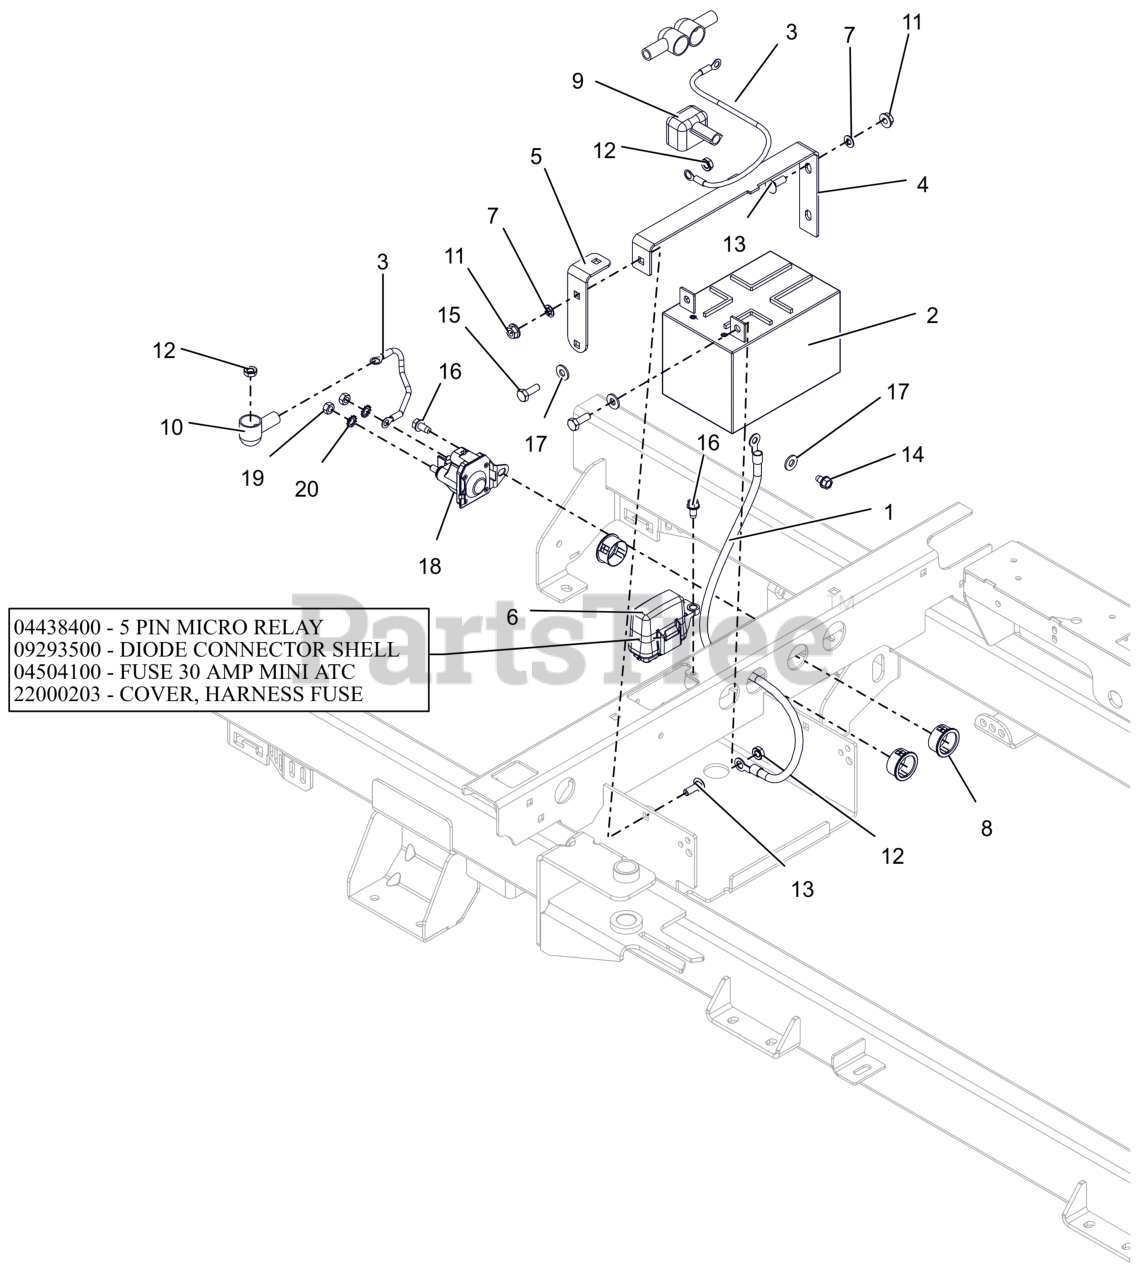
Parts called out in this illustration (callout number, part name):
1	CABLE-NEGATIVE BATTERY 24.00"
2	BATTERY, 12V 12A-190CCA
3	CABLE,POS W/2 1/4 RING 15.0 LG
4	BRKT, BATTERY HOLD-DOWN
5	BRKT, BATTERY HOLD DOWN
6	HARNESS, WIRE-4POS KEY IKON/ZT
6	RELAY,MICRO5 TERML W/RESISTOR
6	DIODE, CONNECTOR SHELL
6	FUSE,30 AMP MINI-ATC
6	COVER, FUSE
7	NUT-PUSH .25X.50 O.D.
8	BSHG, PANEL SNAP .937X1.11X.56
9	INSULATOR
10	BOOT, EYELET TERMINAL
11	NUT-LK-TOP-FLG .250-20 GF ZCC
12	NUT-KEPS .250-20 ZCC
13	BLT, RHSN .25-20X.750 G5 ZCC
14	SCR,TAP .25-20X.375 HWH TR ZCC
15	BLT, HEX .25-20X.75 G5 ZCC
16	SCR-TAP .25-20X.50 HWH ZCC
17	WSHR,FLT .281X.625X.065 ZCC
18	SOLENOID, STARTER (SEALED)
19	NUT-STD M6-1.0 ZCC
20	WSHR,LK-EXT.262X.502X.026 ZCC
